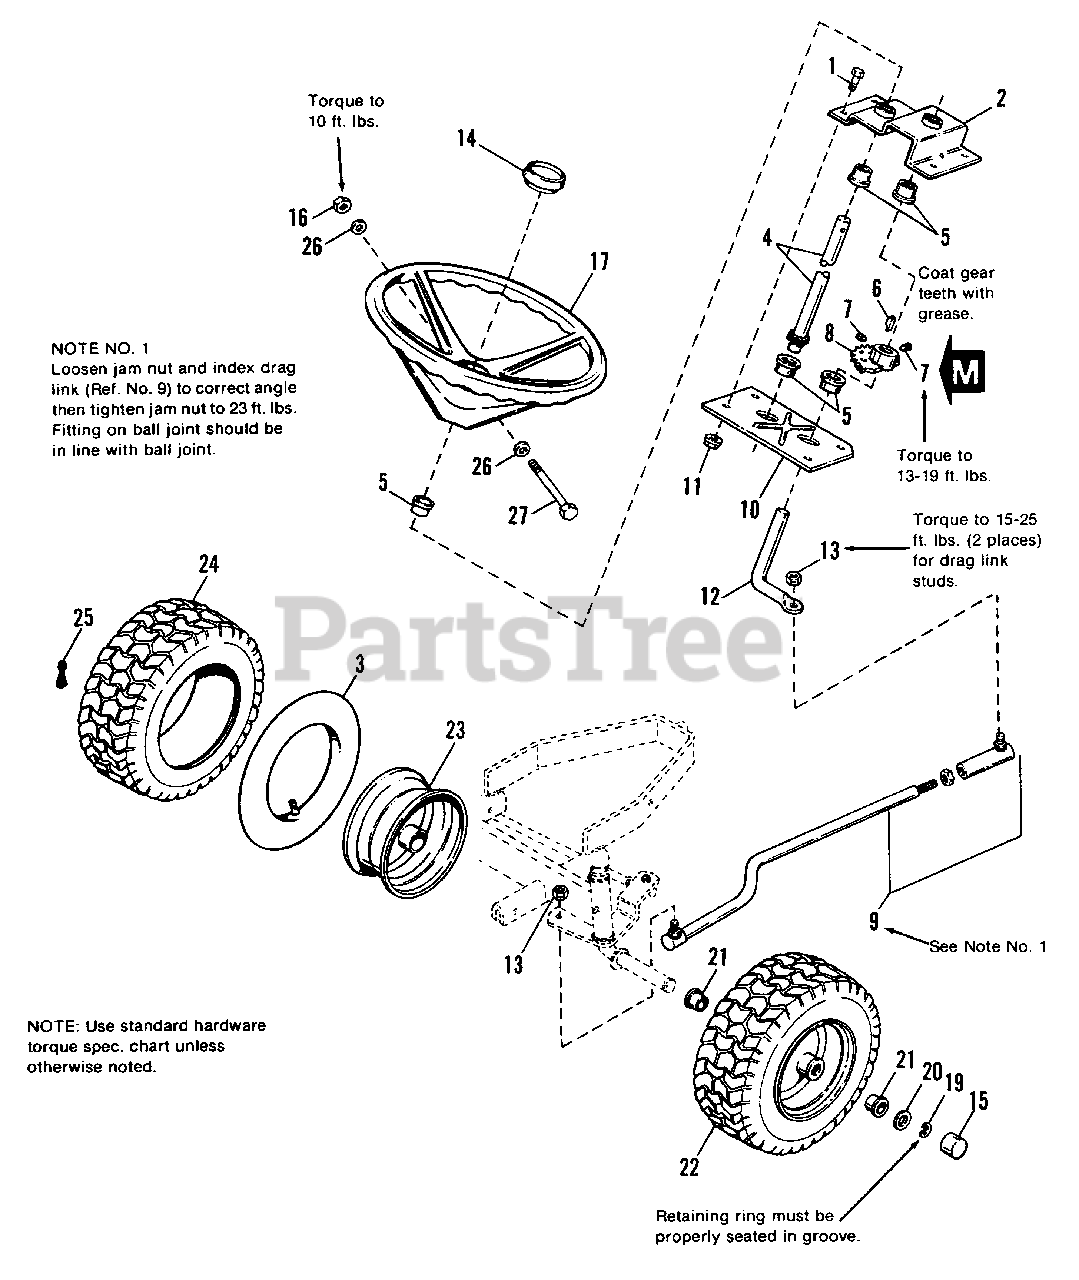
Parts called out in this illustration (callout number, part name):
1	CAPSCREW, 5/16-18 x 3/4
2	TOP PLATE, Steering
3	TUBE (For Service Only)
4	SHAFT ASSY., Steering
7	SETSCREW, 5/16-18 x 1/2, Gr. 8
8	GEAR, Steering
9	LINK ASSY., Drag
10	BASE PLATE, Steering
11	LOCKNUT, Flange, Whiz, 5/16-18
12	ROD, Steering
13	LOCKNUT, Center, 3/8-24
14	CAP, Steering Wheel
15	CAP, Hub, Threaded
16	LOCKNUT, Hex, 5/16-18
17	WHEEL, Steering
18	NUT, Jam, 3/8-24
19	"E" RING, Ext., 3/4
22	WHEEL & TIRE ASSY., 15 x 6.00-6
23	WHEEL, w/o Bearings
24	TIRE (Carlisle)
25	STEM, Valve
26	WASHER, Plain, 5/16
27	BOLT, Hex, 5/16-18 x 3-1/2
